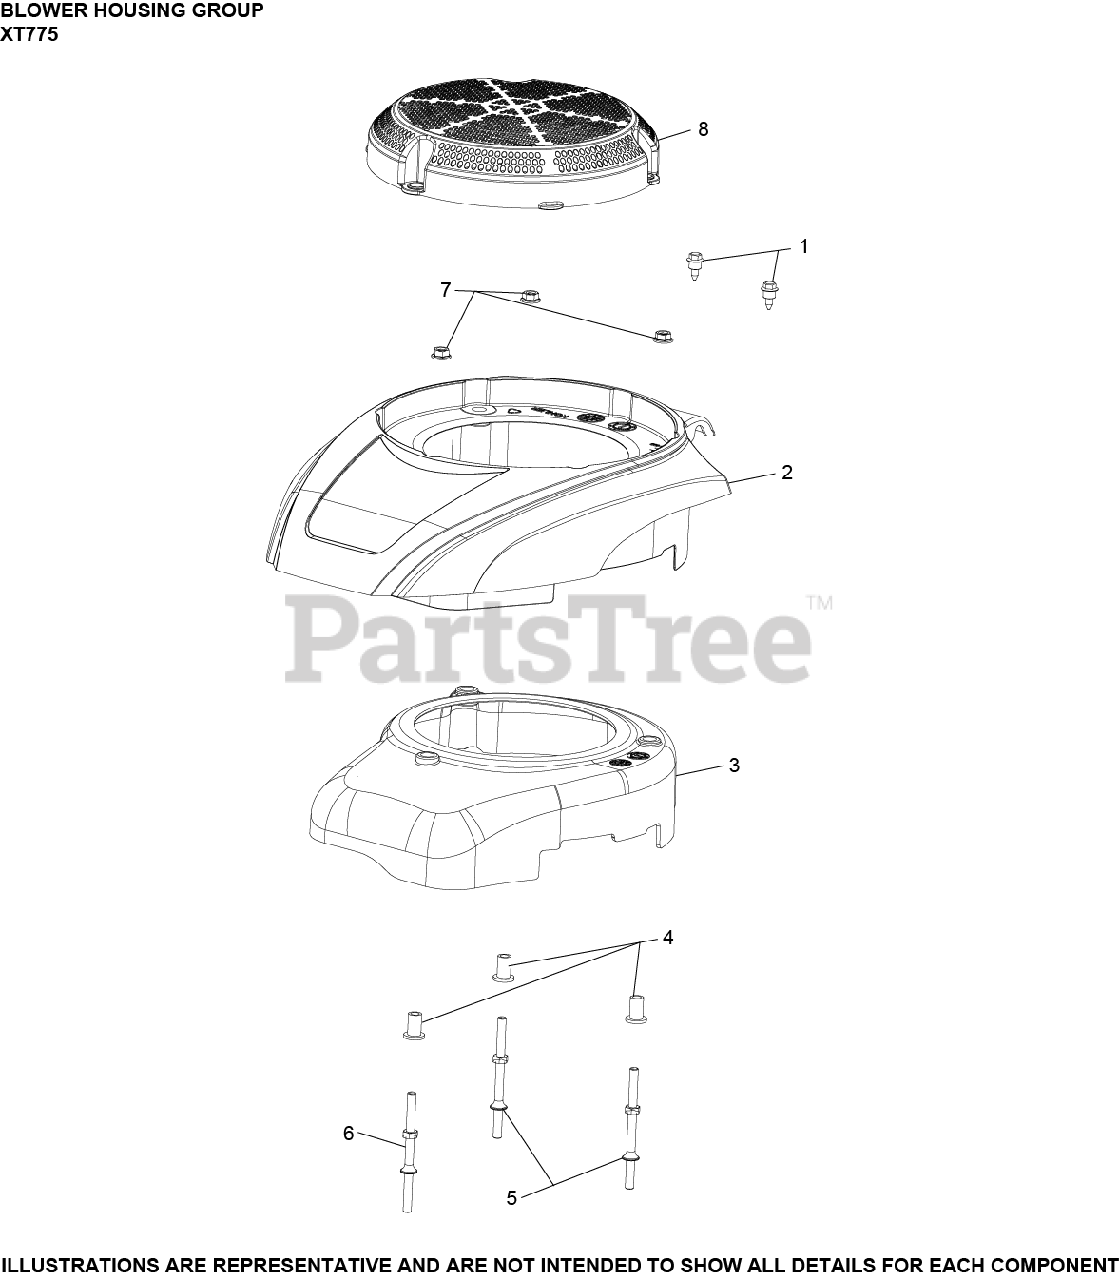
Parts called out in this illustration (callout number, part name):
3	HOUSING, BLOWER
5	STUD, BLOWER HOUSING (IGNITION)
6	STUD, BLOWER HOUSING (IGNITION)
7	NUT, HEX FLANGE (M6)
